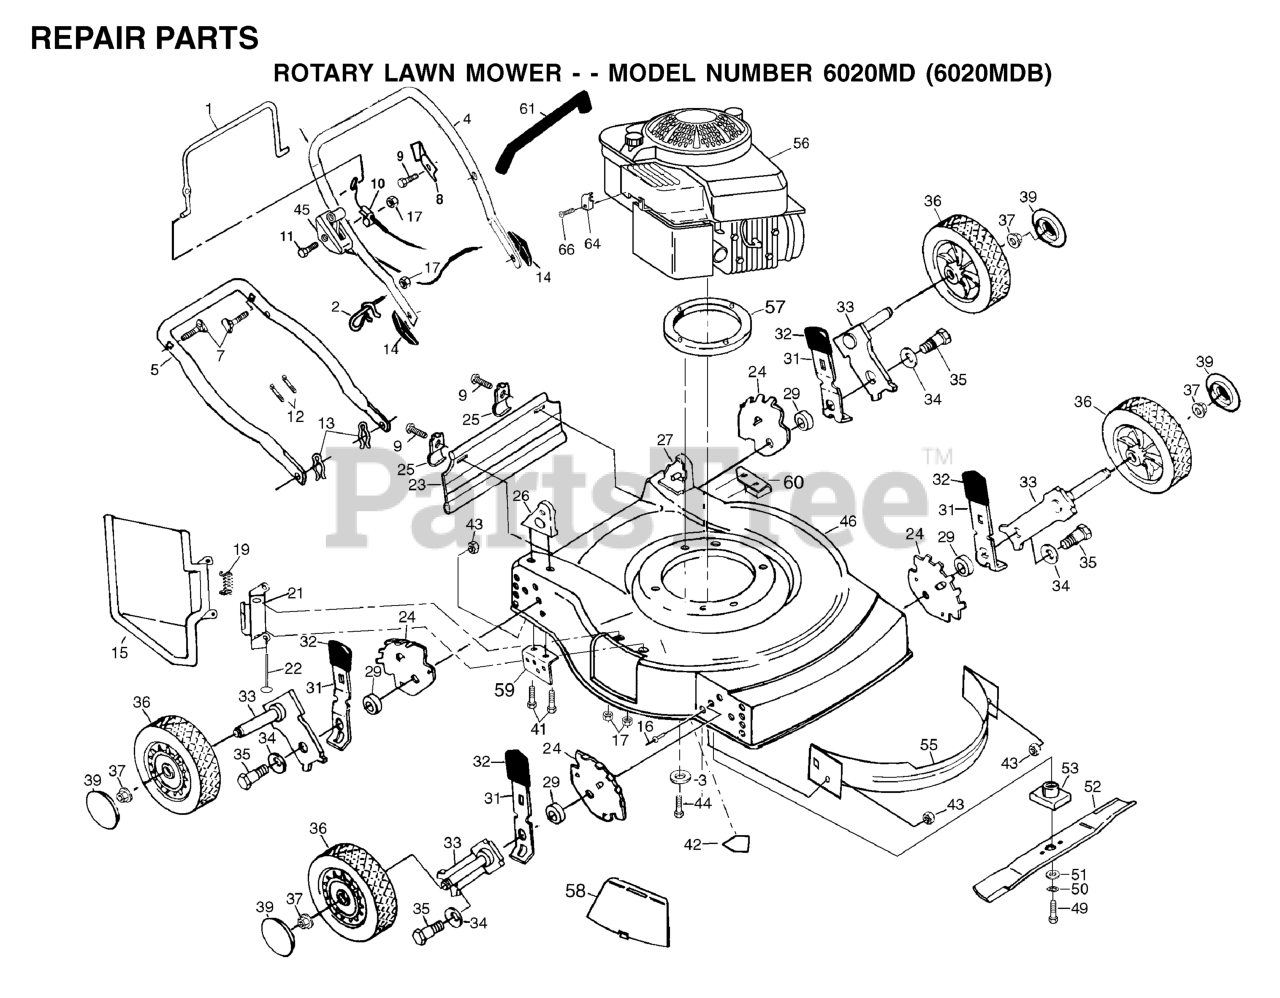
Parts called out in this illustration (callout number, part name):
2	ROPE, GUIDE
4	UPPER HANDLE
5	LOWER HANDLE
7	HANDLE BOLT
8	BRACKET UPSTOP
9	TAPPING SCREW
10	CABLE.MZR.51.RT.SP./PU.
11	SCREW 1/4-20 X 2.12
12	TIE GUIDE
13	HAIRPIN COTTER
14	NUT WING PM
16	RIVET BLIND
17	NUT
21	BRACKET PM
22	ROD.HINGE.COMBI-C
23	REAR SKIRT
24	WHEEL ADJUST BRACKET
25	BRACKET DEFL PM
26	HANDLE BRACKET ASM. RH
27	HANDLE BRACKET ASM. LH
29	RP SPACER HT ADJ
31	SELECTOR SPRING
33	AXLE, REAR
34	WASHER.BELLEVILLE (3 2 LB)
35	BOLT
37	HEX FLANGE LOCKNT
39	CAP.HUB.BLACK.WALK
41	SCREW.5/16-18X3/4
42	DECAL HYT
43	LOCKNUT PM
45	THROTTLE CONTROL
49	SCREW, HEX HD 3/8-24 X 1-3/8
50	LOCKWASHER
51	WASHER,HARDEN
52	BLADE.20.MULCH.(50DK,6020MD)
53	BLADE ADAPTOR
55	REPL BY 532 14 60-26
58	REPL BY 532 12 54-20
59	Bracket Support (Right)
60	BRKT SUPPORT(L)
61	HANDLE GRIP
64	CABLE CLAMP(ENGINE)
66	SCREW.HEX.HEAD.WASHER.10-16
